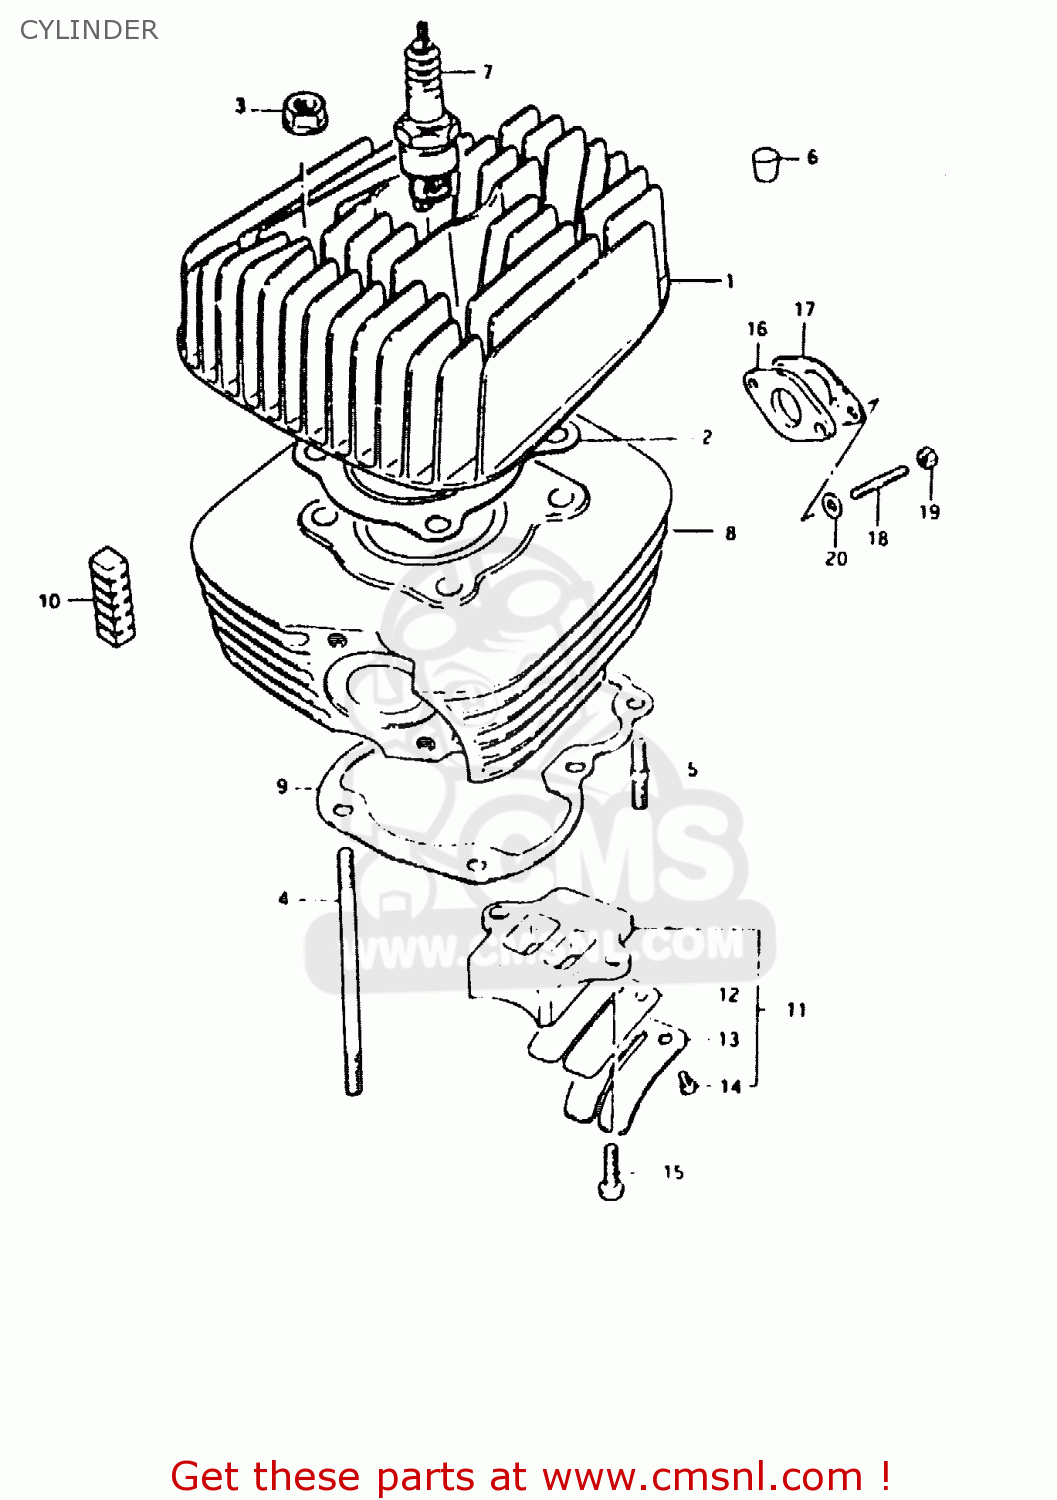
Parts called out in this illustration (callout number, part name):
1	CYLINDER HEAD
2	GASKET,CYLINDER HEAD (NAS)
3	NUT
4	BOLT,STUD
5	STUD 6X16
7	SPARK PLUG (ND,W20EP)
8	CYLINDER
9	GASKET,CYLINDER (MCA)
10	PAD,CYLINDER
16	INSULATOR,CARBURETOR
17	GASKET,CARBURETOR (MCA)
18	STUD BOLT
19	NUT
20	WASHER
